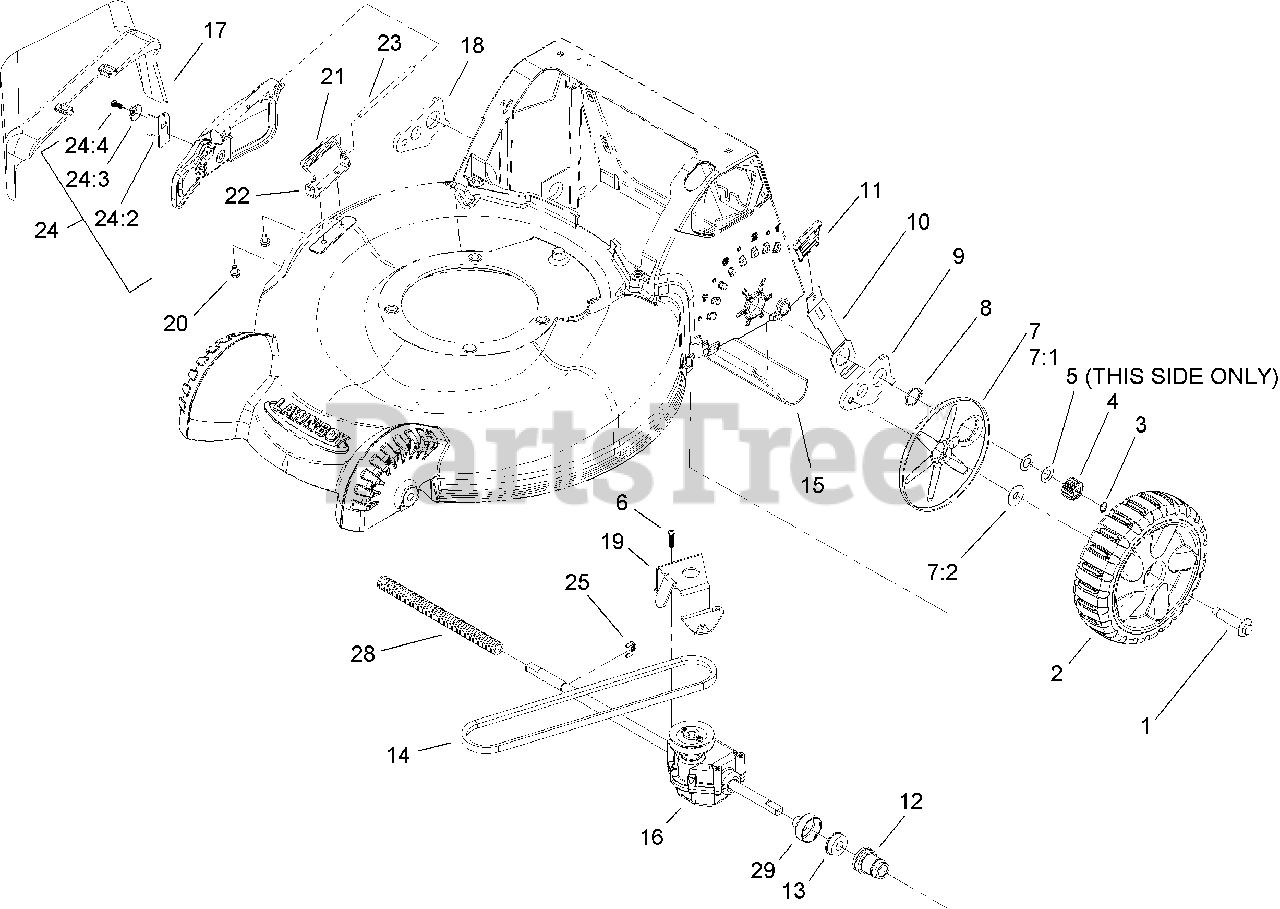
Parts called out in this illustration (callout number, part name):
1	BOLT-SHOULDER
2	REAR WHEEL ASM
3	RING-RETAINING
4	PINION
5	WASHER-PLAIN
6	SCREW-PLASTITE
7	WHEEL COVER ASM
7:1	COVER-WHEEL
7:2	WASHER-STEPPED
8	RING-RETAINING
9	ARM-REAR PIVOT, LH
10	ARM-SPRING, REAR
12	RETAINER-BEARING
13	BEARING-BALL
15	SHIELD-TRAILING
16	TRANSMISSION ASM
17	CHUTE-DISCHARGE, SIDE
18	ARM-REAR PIVOT, RH
19	BRACKET-TRANSMISSION
20	SCREW-HWH
21	SPRING-TORSION
22	BRACKET-COVER
23	ROD-COVER
24	DISCHARGE DOOR ASM
24:2	LATCH-DOOR
24:3	CAP-DOOR
24:4	SCREW-PLASTITE
25	RING-CLIP, LOCKING
28	COVER-SHAFT, DRIVE
29	CAP-BEARING
